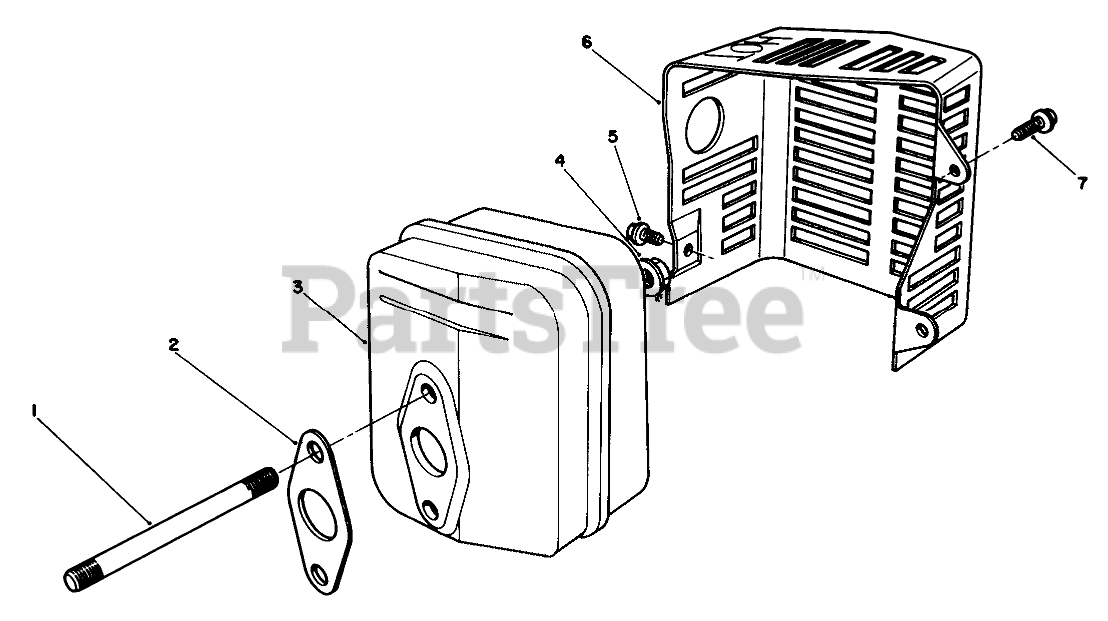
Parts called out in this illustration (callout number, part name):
1	Stud-Muffler
2	Gasket-Muffler
5	SCREW
6	COVER
